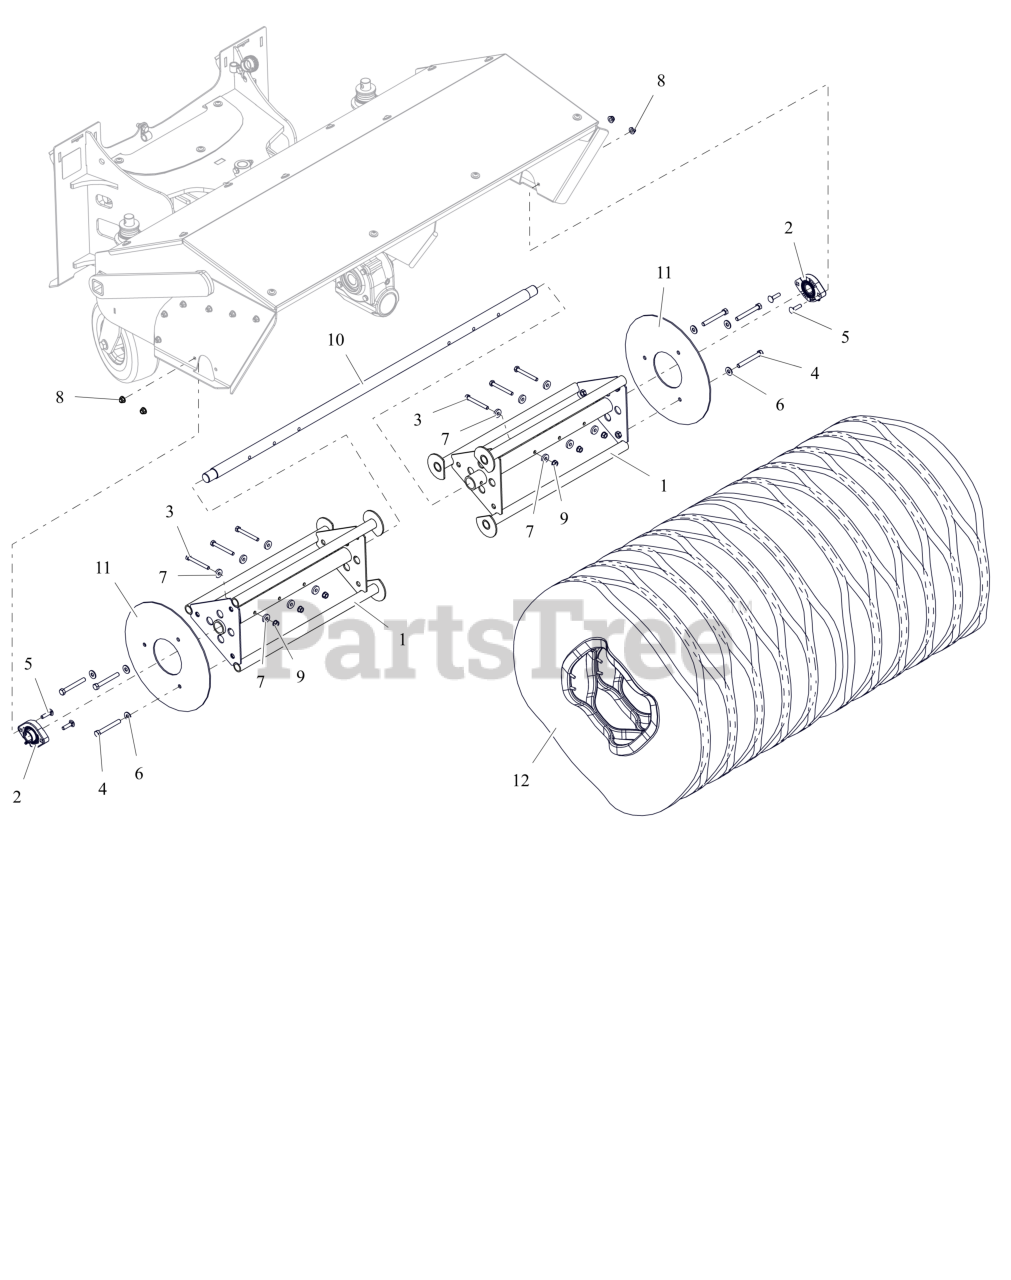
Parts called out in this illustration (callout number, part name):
1	WLDMT, DRIVE CORE
2	KIT, FLANGE BEARING W/HARDWARE
2	BEARING, FLANGE
3	BLT, HEX .31-18X2.75 G5 ZCC
4	BLT, HEX .38-16X3.00F G5 ZCC
5	BLT, RHSN .31-18X1.25 G5 ZCC
6	WSHR,FLT .375X.875X.083 ZCC
7	WSHR, FLT .328X.870X.179 ZCC
8	NUT,LK-NYL-FLG .31-18 G5ZC120
9	NUT,LK-CTR-FLG .31-18 GF ZCC
10	SHAFT, BRUSH
11	PLATE, END RETAINER
12	BRISTLE REPLACEMENT - SET OF 22
